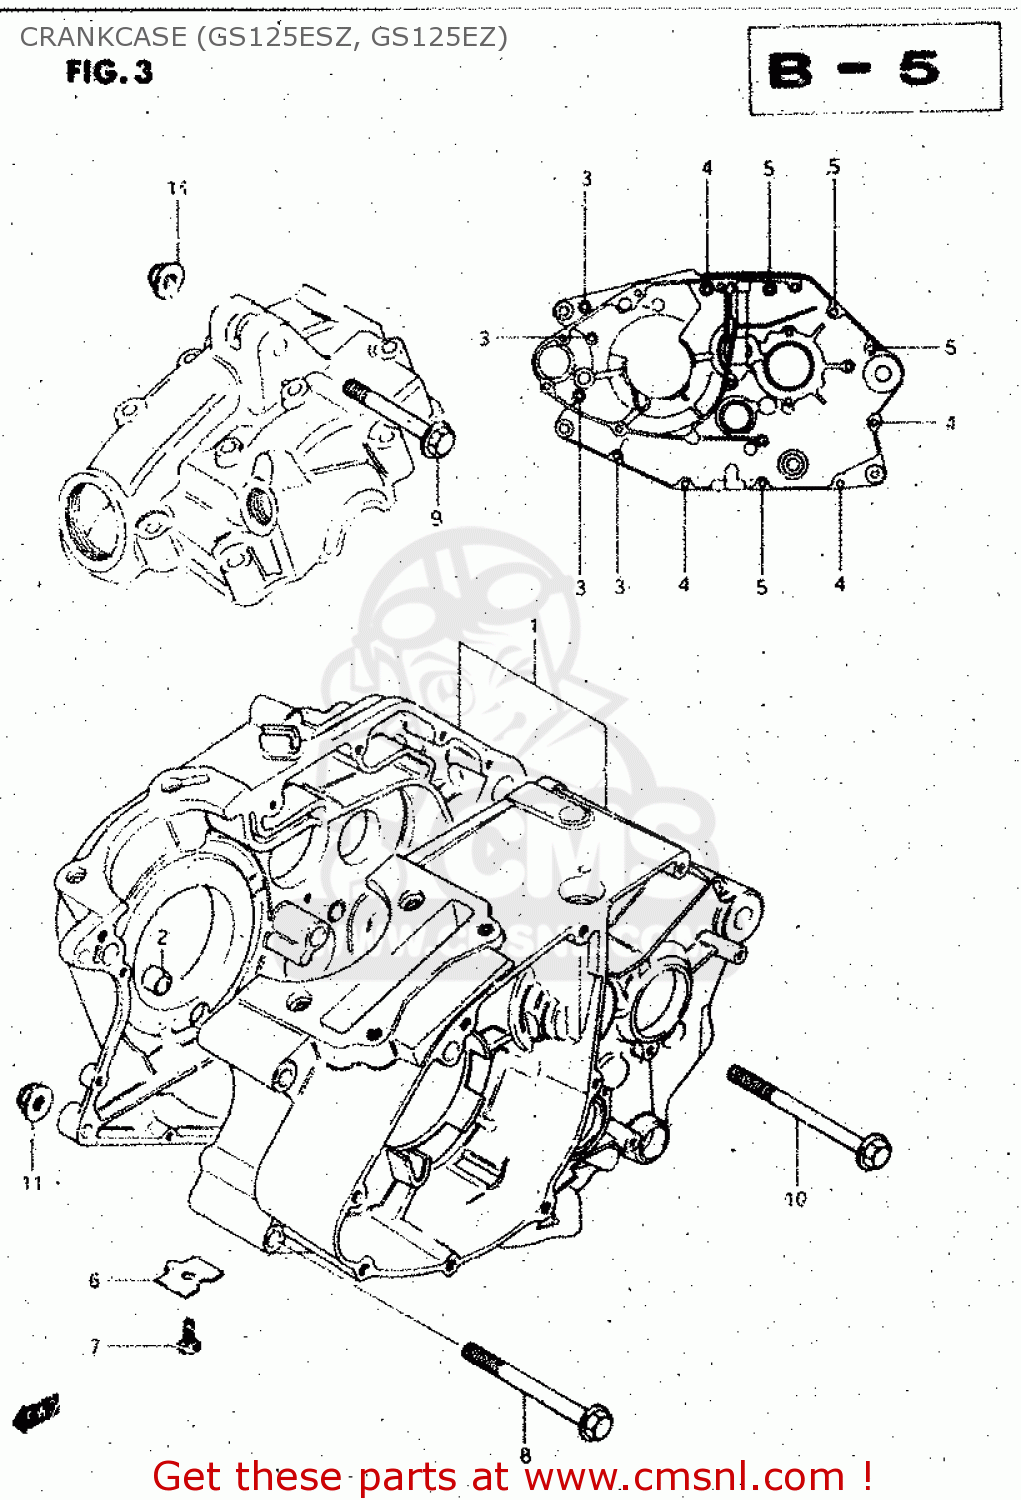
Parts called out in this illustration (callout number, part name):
1	CRANKCASE SET
2	PIN
3	BOLT
4	BOLT
5	BOLT
6	PLATE,OIL GALLERY PLUG
7	BOLT
8	BOLT(8X80)
9	BOLT
10	BOLT
11	NUT
